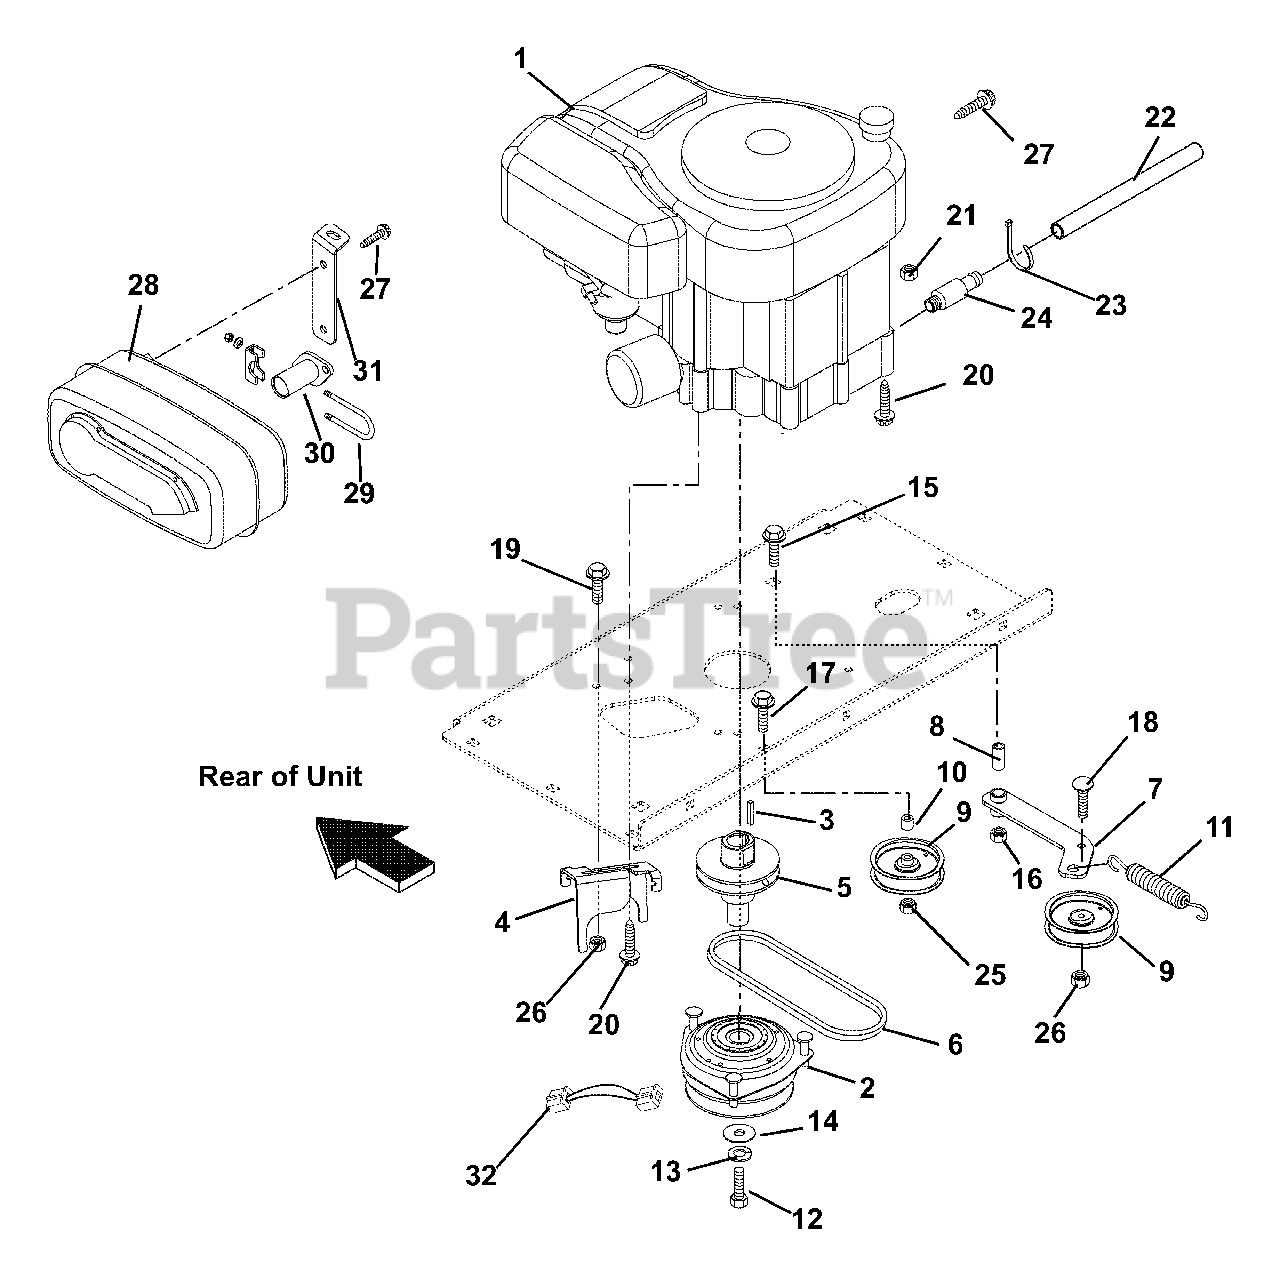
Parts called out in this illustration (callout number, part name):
1	Engine, 15HP Kohler
2	Clutch/Brake, Electric
3	Key, Square .25 x 1.50 x .25 SAE 8630 OR SAE 1035
4	Clutch Stop
5	Extension Shaft
6	V-Belt A-Section 25.1 x .495
7	Weldment, Idler
8	Bushing, Sleeve .50 x .75 x 1.56
9	Pulley, Idler 4.00
11	Spring, Extension
12	Bolt, Hex .44-20 x 4.50 Grade 8
13	Washer, Locking .44 x .109 Regular
14	Washer, Flat Steel .469 x 2.00 x .25
15	Bolt, Round Head Square Neck .50-13 x 2.50 Grade 5
16	Nut, Locking Top Flange .50-13
17	Bolt, Round Head Square Neck .38-16 x 2.50 Grade 5
18	Bolt, Round Head Square Neck .38-16 x 1.25 Grade 5
19	Bolt, Hex .38-16 x 1.00 Grade 5
20	Screw, Tapping .38-16 x 1.00 Hex Washer Head
21	Nut 5/16-18 Flange Nyloc
22	Tube, Oil Drain
23	Cable Tie
24	Valve, Oil Drain
25	Nut, Locking, Jam, Center .375-16
26	Nut, .38-16 Flange Nyloc
27	Screw, Tapping .25-20 x .50 Hex Washer Head
28	Muffler, Kohler Courage Single
29	Clamp, Muffler
30	Weldment, Manifold
31	Bracket, Muffler
32	Adapter, Clutch Harness
